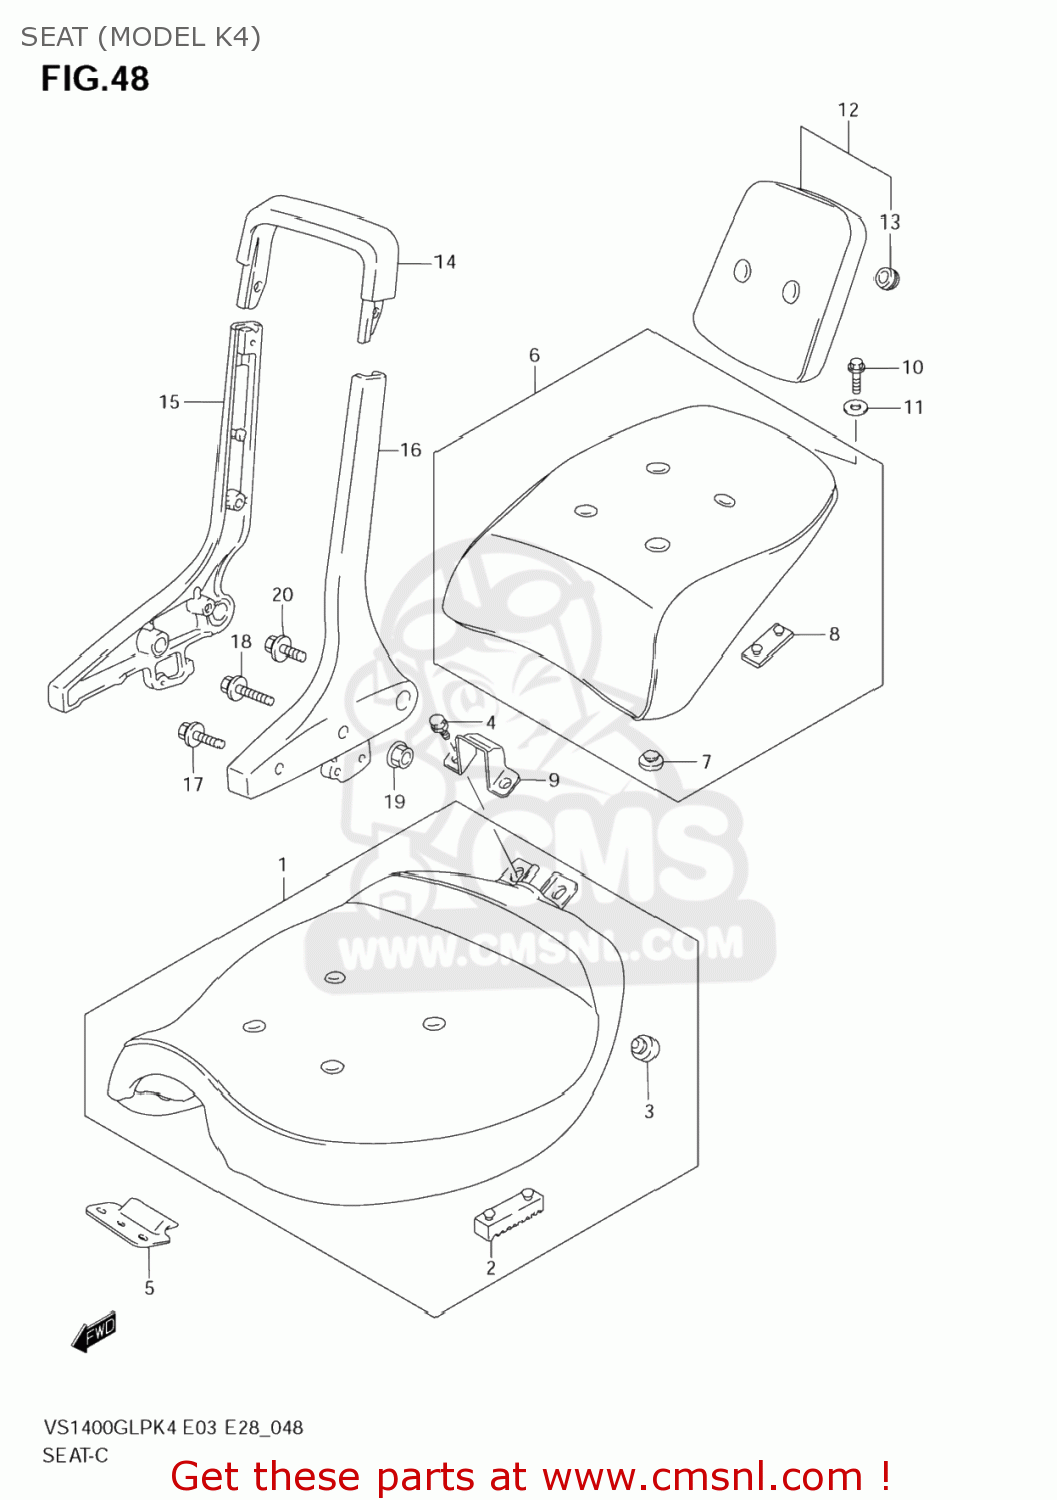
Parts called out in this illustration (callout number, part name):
1	SEAT ASSY
2	CUSHION,SEAT
3	CUSHION
4	BOLT
5	BRACKET,SEAT FR
6	SEAT ASSY,PILLION
7	CUSHION
8	CUSHION,PILLION SEAT RR
9	BRACKET,PILLION SEAT FR
10	BOLT(6X17.5)
11	WASHER(9.5X20X1)
12	PAD ASSY,SEAT
13	CUSHION
14	HANDLE,PILLION RIDER UPR
15	HANDLE,PILLION RIDER,RIGHT
16	HANDLE,PILLION RIDER,LEFT
17	BOLT, FRONT
18	BOLT
19	NUT
20	BOLT, REAR
